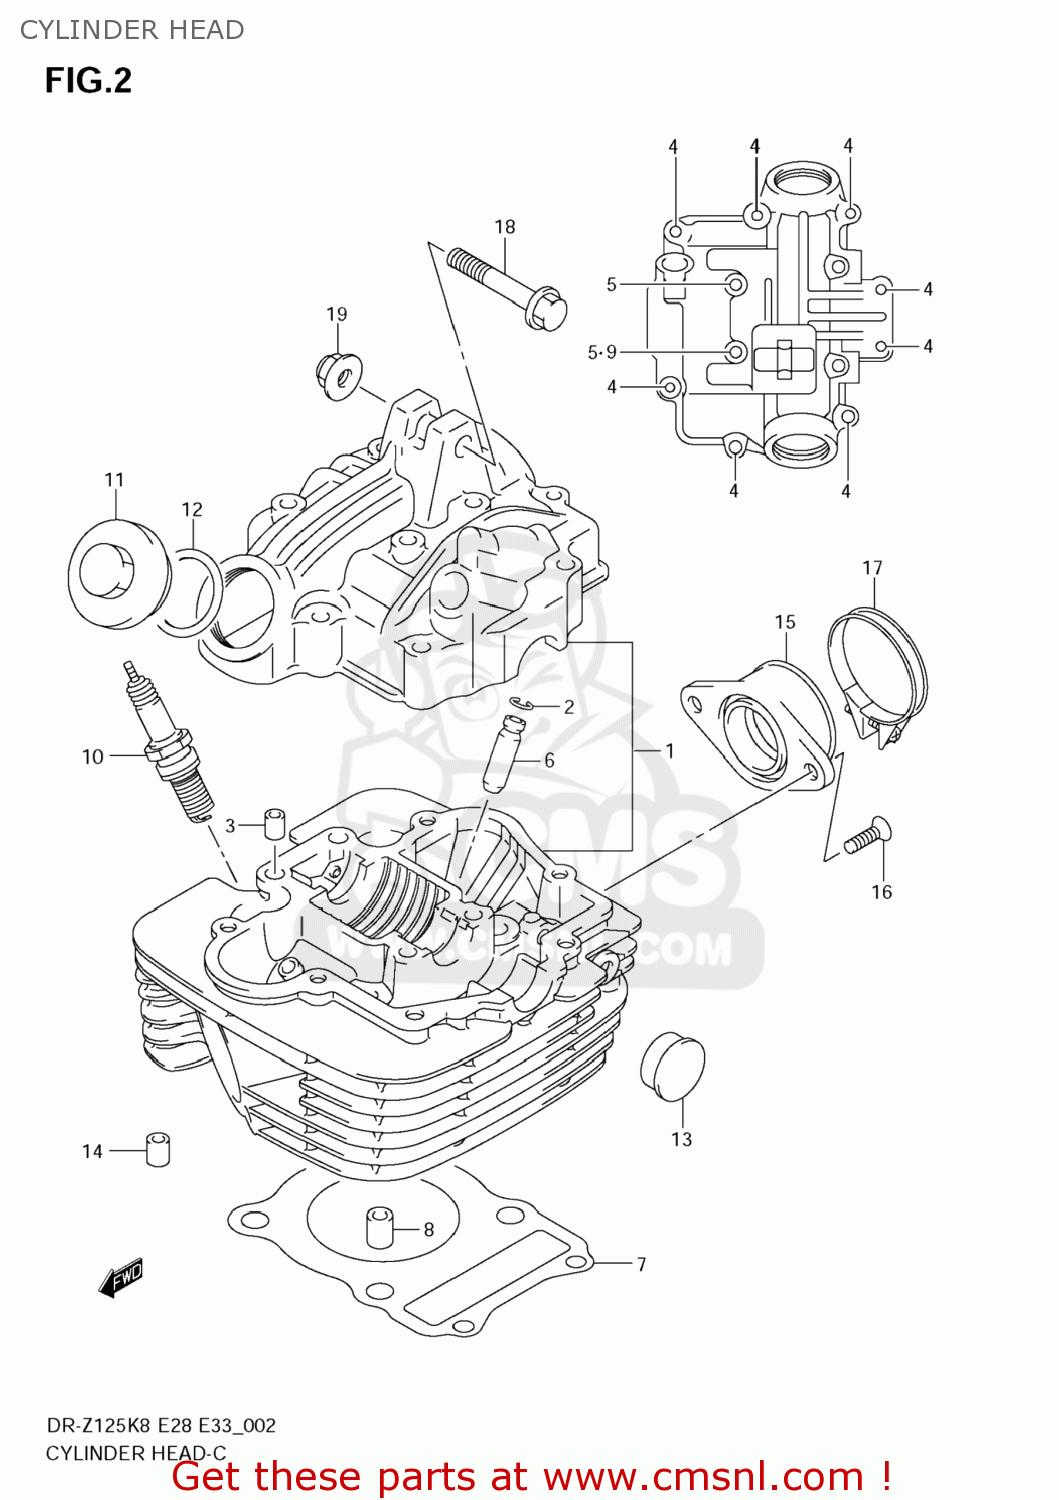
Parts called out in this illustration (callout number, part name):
1	HEAD ASSY,CYLINDER
2	RING,SNAP
3	PIN(6.2X8X11)
4	BOLT
5	BOLT
6	GUIDE,VALVE
7	GASKET.CYLINDER HEAD (NAS)
8	PIN
9	GASKET(5.8X13X1.2) (NAS)
10	PLUG,SPARK(DR8EA)
11	CAP,INSPECTION
12	O RING(D:3,ID:29.5)
13	PLUG(OD:22.5)
14	PAD,CYLINDER HEAD
15	PIPE ASSY,INTAKE
16	SCREW
17	CLAMP
18	BOLT(8X50)
19	NUT
